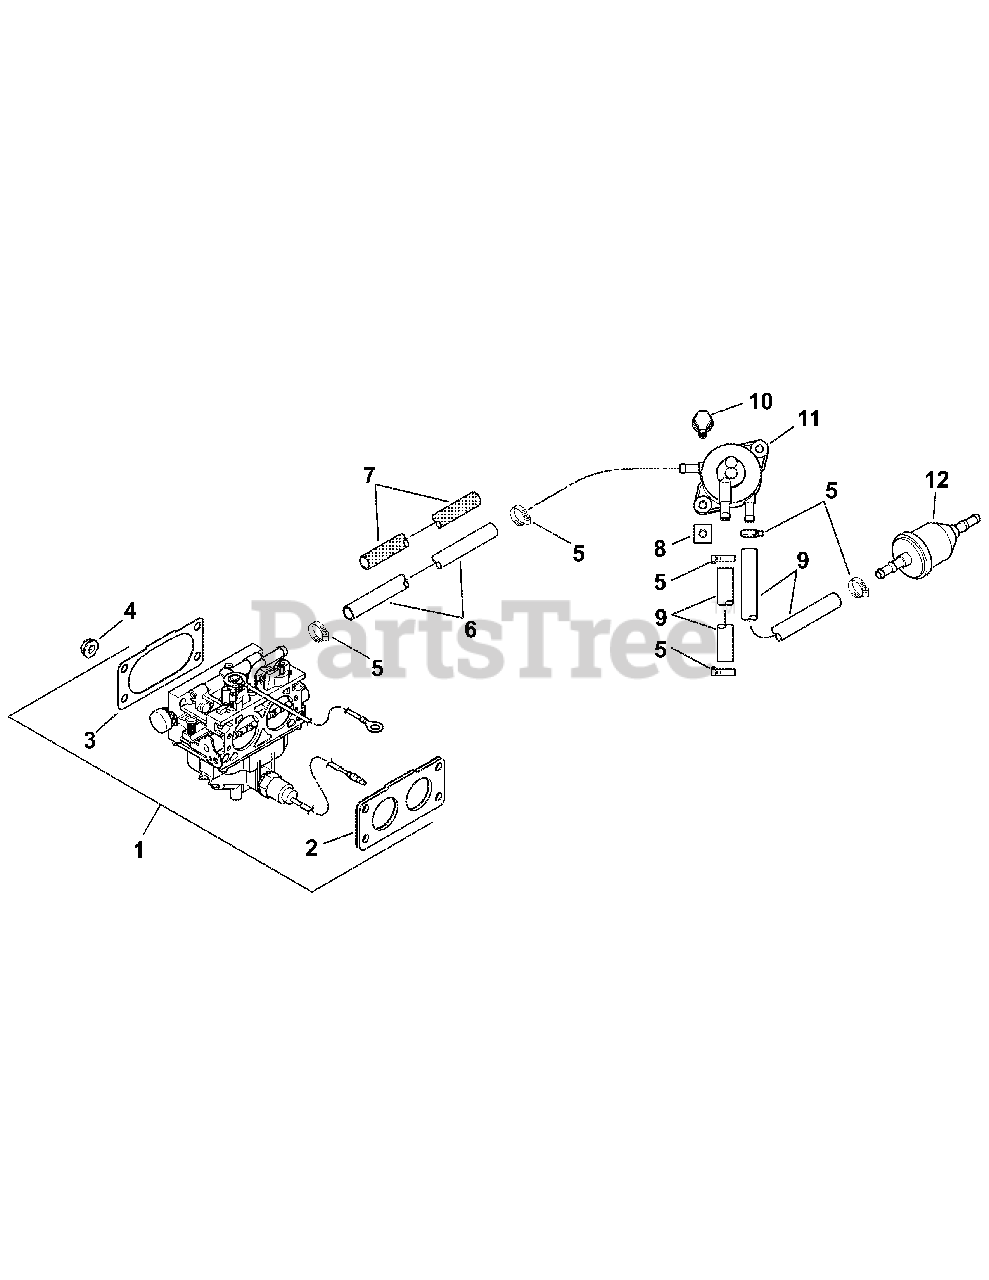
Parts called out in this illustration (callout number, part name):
1	KIT, CARBURETOR W/GASKETS
2	GASKET, CARBURETOR
3	GASKET, AIR CLEANER BASE
4	NUT, FLG M6X1.0
5	CLAMP, HOSE
6	LINE, FLEX 11" PUMP-PULSE
7	SLEEVE, INSULATING 14"
8	NUT, PLASTIC
9	LINE, FUEL
10	SCREW, TAP M6X1.7X18
12	FILTER, FUEL
